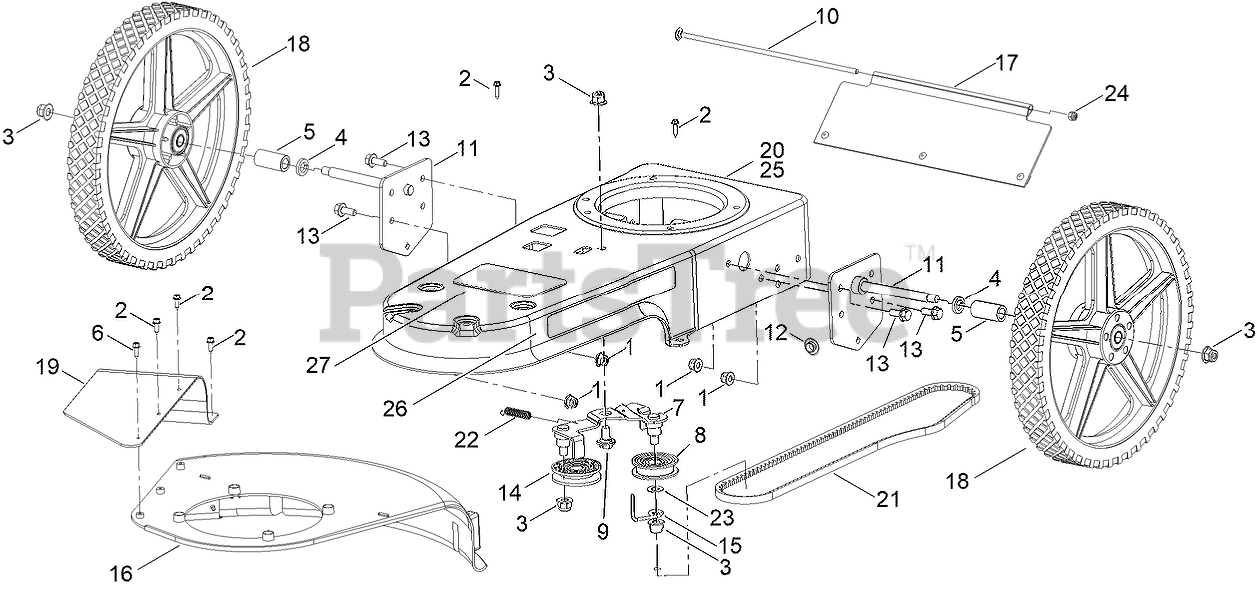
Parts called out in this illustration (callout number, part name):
1	NUT-HEX
2	SCREW-PPH
3	NUT-HEX
4	WASHER-LOCK
5	SPACER-TUBE
6	SCREW-PHWH
7	ARM-IDLER
8	PULLEY-IDLER, FLAT
9	SCREW-HHF
10	BOLT-CARRIAGE
11	AXLE ASM
12	GROMMET
13	SCREW-HHF
14	PULLEY-IDLER
15	GUIDE-BELT
16	SHIELD-TRIMMER
17	SHIELD-TRAILING
18	WHEEL ASM
19	CHUTE-DISCHARGE
20	FRAME-DECK
21	BELT-V
22	SPRING-EXTENSION
23	WASHER-PLAIN
24	NUT-HEX
25	DECAL-WARNING
27	DECAL-DECK
